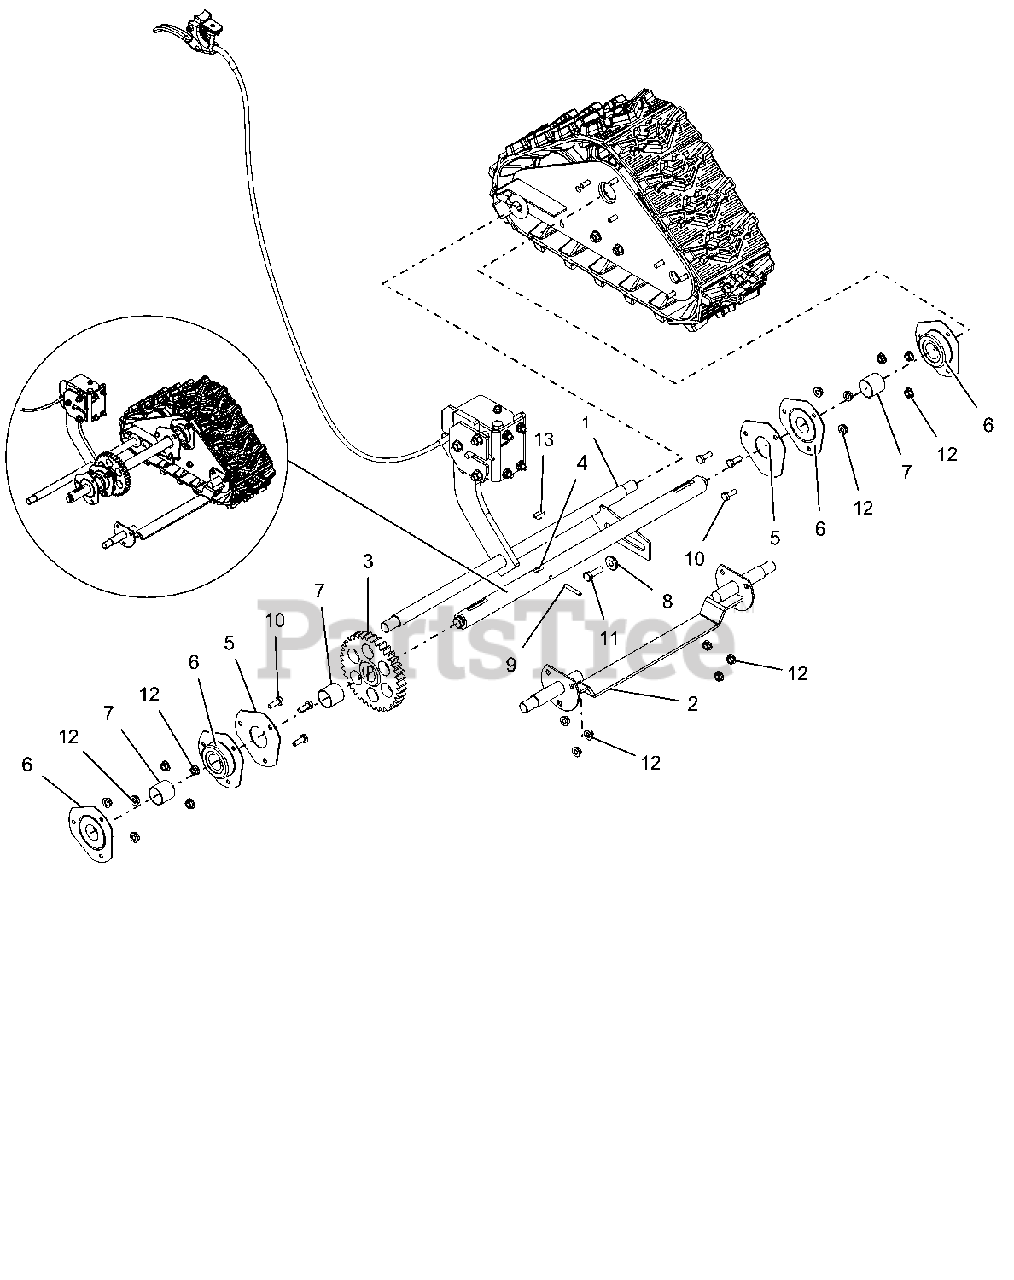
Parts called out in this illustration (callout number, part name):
1	AXLE, REAR - DELUXE TRACK
2	AXLE, FRONT-COMPACT TRACK
3	GEAR, SPUR
4	AXLE, TRACK-DELUXE
5	PLATE, BEARING SPACER
6	BRG-FLG 1.003/1.000 3 BOLT
7	BSHG-SLV, 1.012X1.125X1.00
8	BSHG-FLG .325X.499X.3X.875
9	PIN-ROLL .188X1.25
10	@BLT-HEX .25-20X.75 GR5 YWZC
11	@BLT-HEX .31-18X1.00 GR5 YWZC
12	@NUT-LK-CTR-FLG .25-20 YWZC
13	KEY-WDRF .25X.750X.313 SAE91
